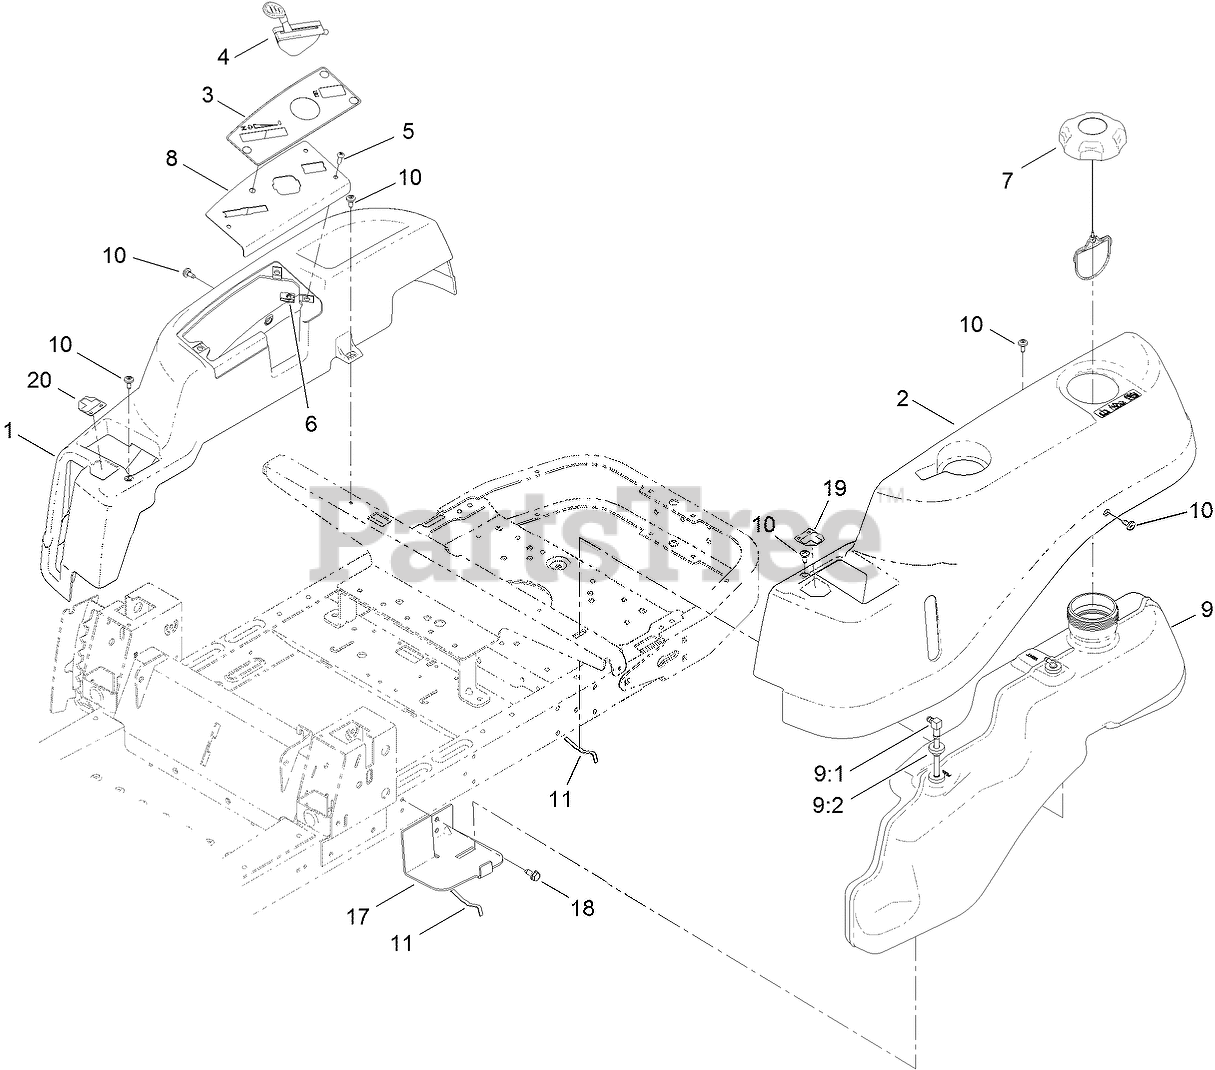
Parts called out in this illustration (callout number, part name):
1	POD-RH
2	POD-LH
3	DECAL-PANEL, CONTROL
4	CABLE-THROTTLE AND CHOKE
5	SCREW-PRH
7	CAP-FUEL, RATCHETING
8	PLATE-CONTROL
9	FUEL TANK ASM
9:1	CONNECTOR-ELBOW, 90 DEG
9:2	BUSHING
10	SCREW-SHOULDER
11	SPRING
17	SUPPORT-TANK, FRONT
18	SCREW-HWHTF
19	DECAL-CONTROL LEVER, LH
20	DECAL-CONTROL LEVER, RH
